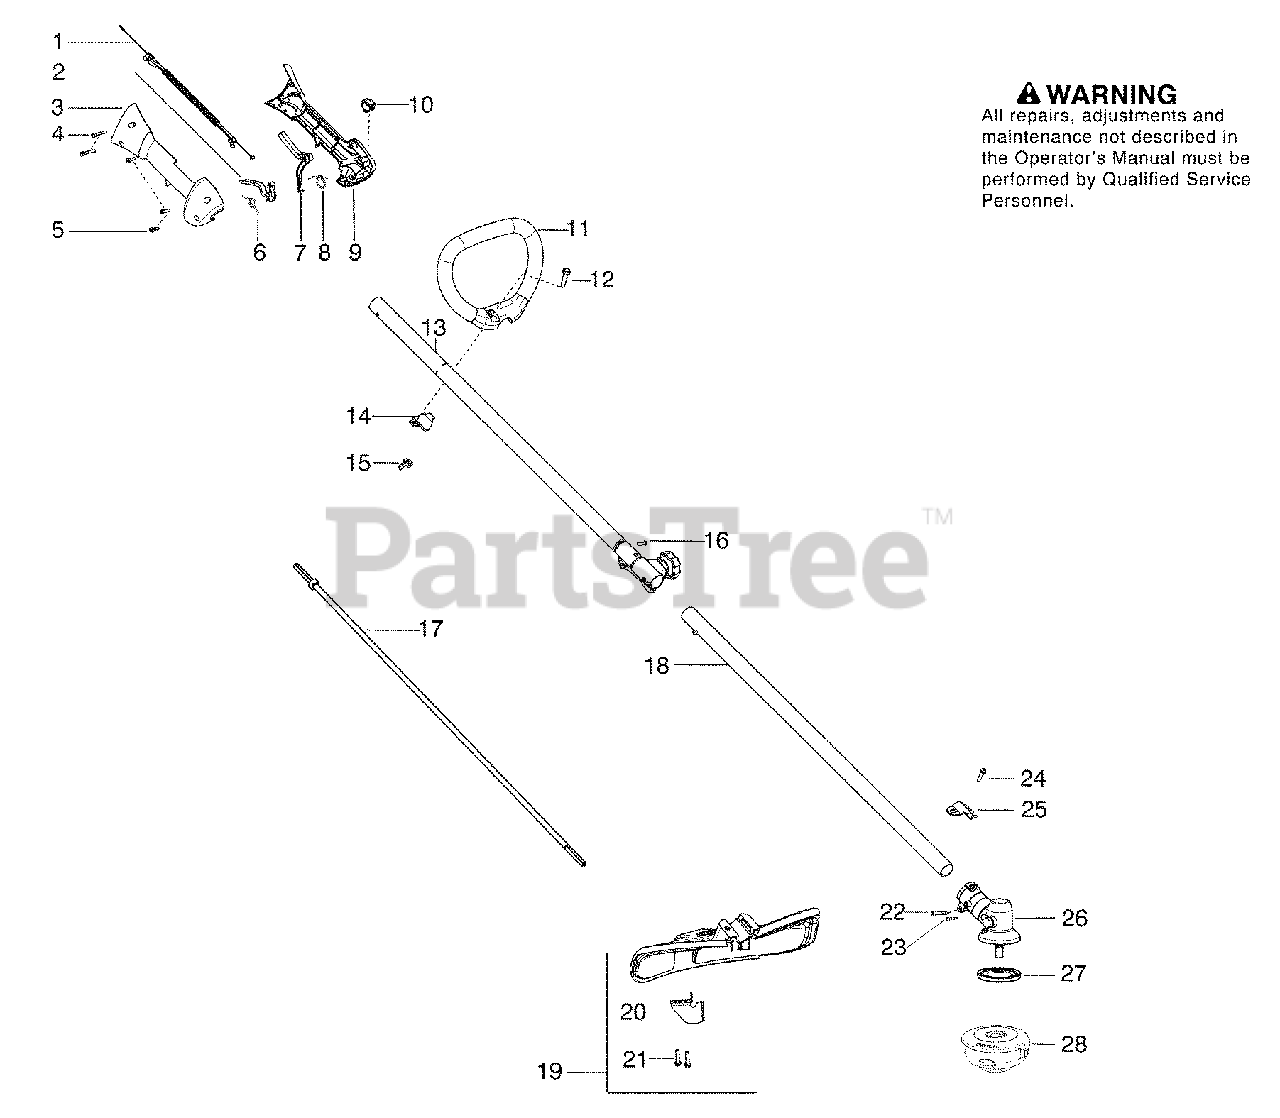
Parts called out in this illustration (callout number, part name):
1	Assy - Cable/Wire Harness
3	Housing - Throttle (RH)
6	Spring - Trigger
7	Lockout - Throttle
8	Spring - Lockout
9	Housing - Throttle (LH)
10	Kit - Switch
11	Handle - Assist
13	Kit - Driveshaft Upper
14	Clamp - Handle Assist
15	Wingnut
18	Kit - Lower Shaft
19	Kit - Shield
20	Limiter - Line
25	Bracket - Shield
26	Assy - Gearbox
27	Driver Disc
28	Assy - T25 Cutting Head
